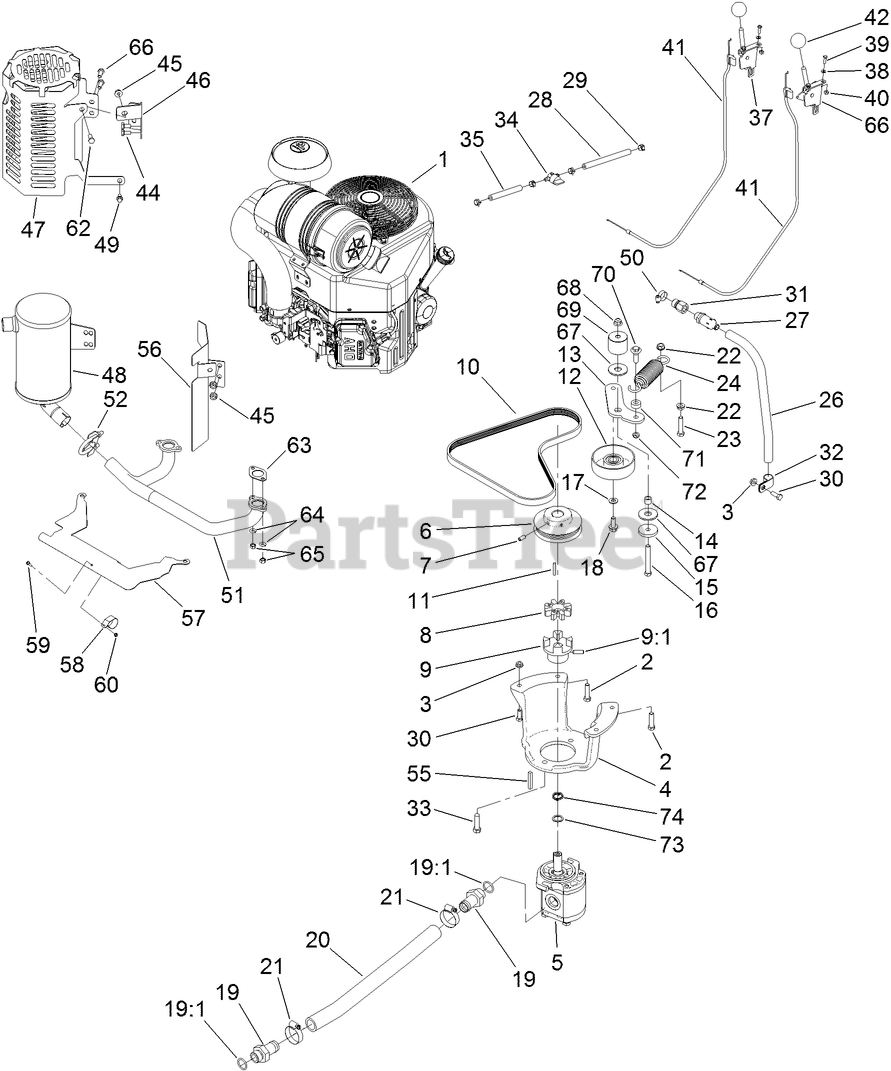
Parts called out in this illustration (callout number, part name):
1	ENGINE-KAWASAKI, FX730V
2	SCREW-HH
3	NUT-HF
4	MOUNT-PUMP
5	GEAR PUMP ASM
6	PULLEY-ENGINE
7	SCREW-SET, HSH
8	COUPLER-SPIDER
9	COUPLER-FLEX
9:1	SCREW-SET
10	BELT-V
11	KEY-SQUARE
12	PULLEY-IDLER
13	ARM-IDLER
14	BUSHING-LEVER, LIFT
15	WASHER-PLAIN
16	SCREW-HH
17	WASHER-FLAT
18	SCREW-HHF
19	FITTING
19:1	O-RING
20	HOSE-SUCTION
22	NUT-HHF, WHIZ
23	SCREW-HH
24	SPRING-EXTENSION
26	HOSE-VENT
27	VALVE-DRAIN, OIL
28	HOSE-FUEL
29	CLAMP-HOSE
30	SCREW-HH
31	Adapter
32	CLAMP-R
33	SCREW-HH
34	VALVE-FUEL
35	HOSE-FUEL
37	LEVER-CONTROL
38	WASHER-FLAT
40	NUT-LOCK, NI
41	CABLE-CONTROL
44	SCREW-HH
45	NUT-HF
46	BRACKET-MOUNT, MUFFLER
47	SHIELD-MUFFLER
48	MUFFLER
49	SCREW-HHF
50	CLAMP-HOSE
51	MANIFOLD
52	CLAMP-MUFFLER
55	KEY-SQUARE
56	BRACKET-SHIELD, HEAT
57	PLATE-SHIELD, HEAT
59	SCREW-PAN
60	NUT-HEX
62	SCREW-HH
63	GASKET-EXHAUST
64	WASHER-SPRING
65	NUT-HEX
66	LEVER-CONTROL
67	WASHER-FRICTION, COMPOSITE
68	NUT-HF, NI
69	SPACER-IDLER
70	SCREW-SHOULDER, HWH
71	SPACER
72	NUT-LOCK, NI
73	WASHER-THRUST
74	WASHER-WAVE
